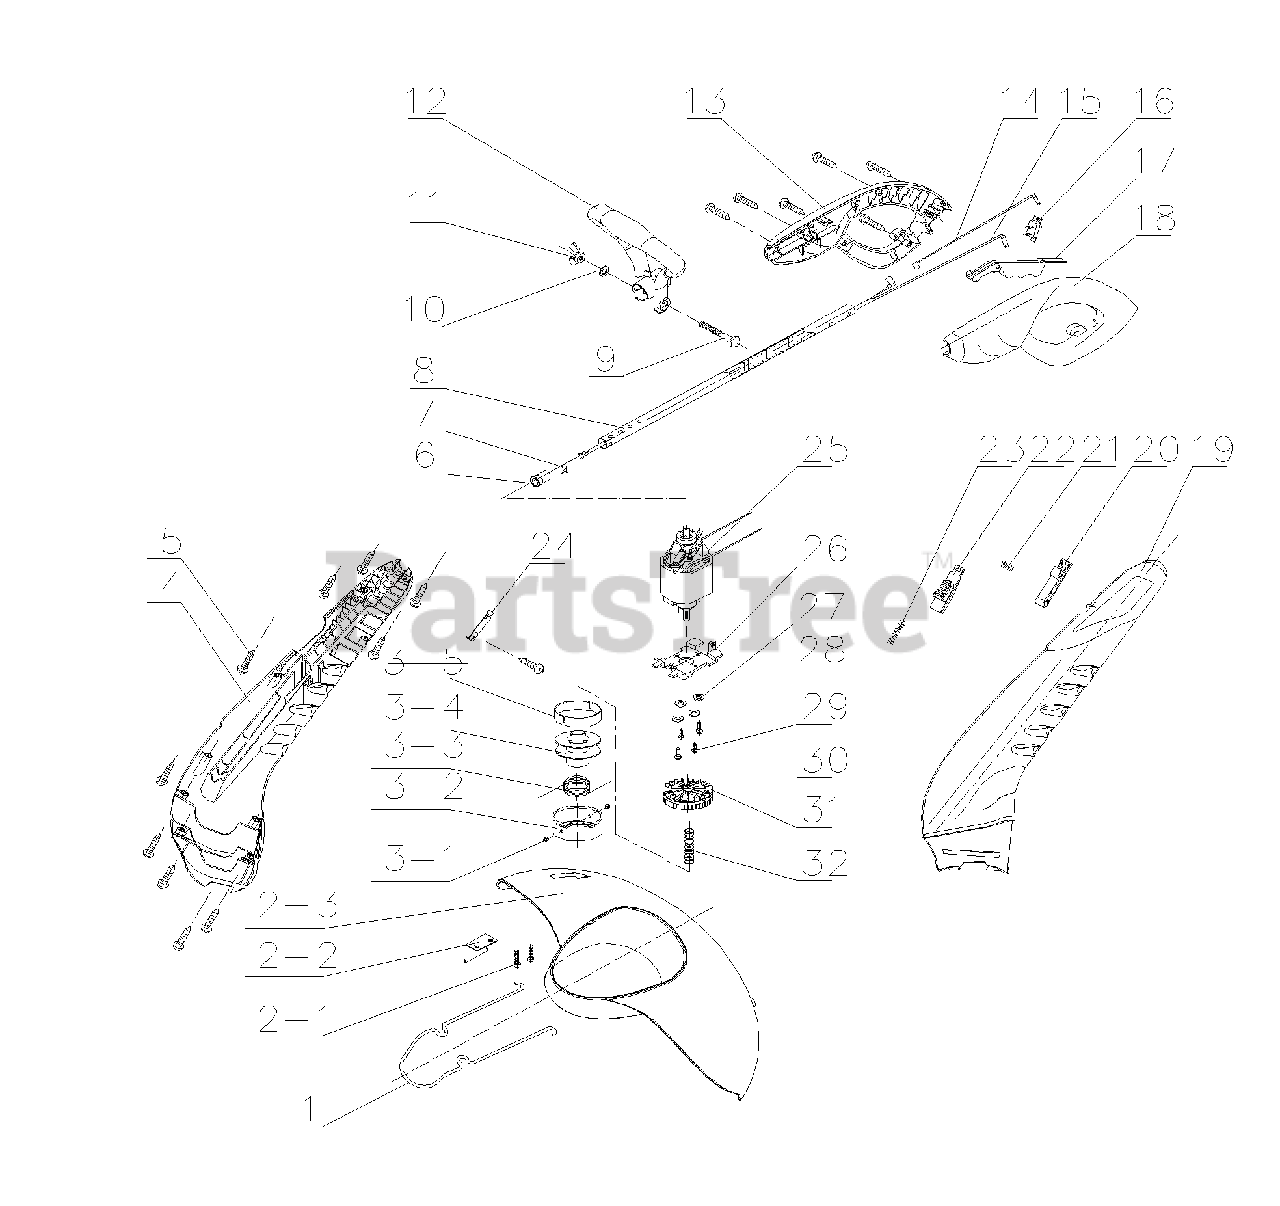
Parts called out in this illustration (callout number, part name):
1	PROJECTIVE GUARD
2	GUARD ASS'Y
3	SPOOL CARRIER ASS'Y
4	HOUSING (R)
7	SNAP BUTTON
12	CENTRAL HANDGRIP
13	UPPER HANDGRIP (R)
18	UPPER HANDGRIP (L)
19	HOUSING (L)
25	MOTOR 120V
26	MOTOR PLATE
31	CUTTER ASS'Y
